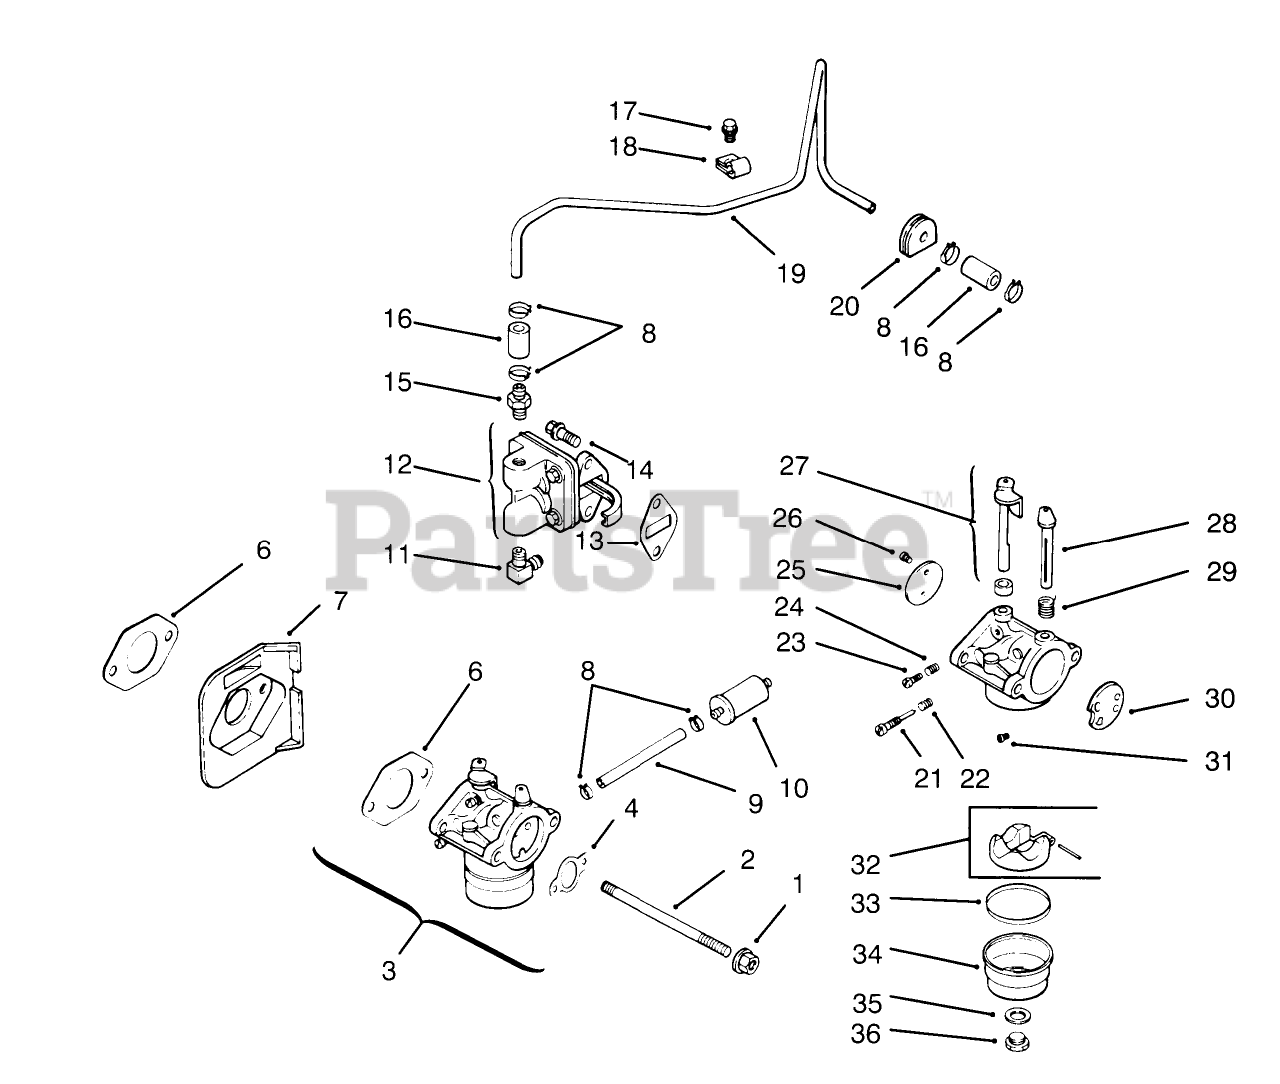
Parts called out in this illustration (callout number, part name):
2	Stud M6x1.0x110 (Only On: 72042,72043,72062,72063)
3	Kit-Carb INCL 4/6/21 -36 (Only On: 72042,72043,72062,72063)
4	Gasket-Air Cleaner (Only On: 72042, 72043, 72062, 72063)
6	Gasket-Carburetor (Only On: 72042, 72063, 72062, 72043)
7	Deflector-Heat (Only On: 72042,72043,72062,72063)
8	Clamp
9	Line-Fuel 3" (Only On: 72042, 72063, 72062, 72043)
10	Filter-Fuel (Only On: 72042,72043,72062,72063)
11	Connector
12	Kit-Pump INCL 13-14 (Only On: 72042,72043,72062,72063)
13	Gasket-Fuel Pump (Only On: 72042,72043,72062,72063)
14	Screw
15	Connector
16	Line-Fuel 1.25 Inch (Only On: 72042,72043,72062,72063)
18	Clamp-Fuel Line (Only On: 72042, 72063, 72062, 72043)
19	Line-Fuel (Only On: 72042,72043,72062,72063)
20	Grommet (Only On: 72042, 72063, 72062, 72043)
21	Needle-Idle Fuel Adjust (Only On: 72042, 72063, 72062, 72043)
22	Spring-Idle Fuel (Only On: 72042, 72063, 72062, 72043)
23	Screw-Idle Speed Adjust (Only On: 72042,72043,72062,72063)
24	Spring-Idle Fuel (Only On: 72042, 72063, 72062, 72043)
25	Plate-Throttle (Only On: 72042,72043,72062,72063)
26	Screw-Throttle Plate (Only On: 72042,72043,72062,72063)
27	Shaft-W/Lever Seal (Only On: 72042, 72063, 72062, 72043)
28	Shaft-Choke (Only On: 72042. 72063, 72062, 72043)
29	Spring-Choke Return (Only On: 72042,72063, 72062, 72043)
30	Plate-Choke (Only On: 72042, 72063, 72062, 72043)
31	Jet-Main (Only On: 72042, 72063, 72062, 72043)
32	Kit-Float (Only On: 72042,72043,72062,72063)
33	Gasket-Bowl (Only On: 72042,72043,72062,72063)
34	Bowl-Fuel (Only On: 72042, 72063, 72062, 72043)
35	Gasket-Bowl Screw (Only On: 72042, 72063, 72062, 72043)
36	Screw-Fuel Bowl (Only On: 72042, 72063,72062, 72043)
